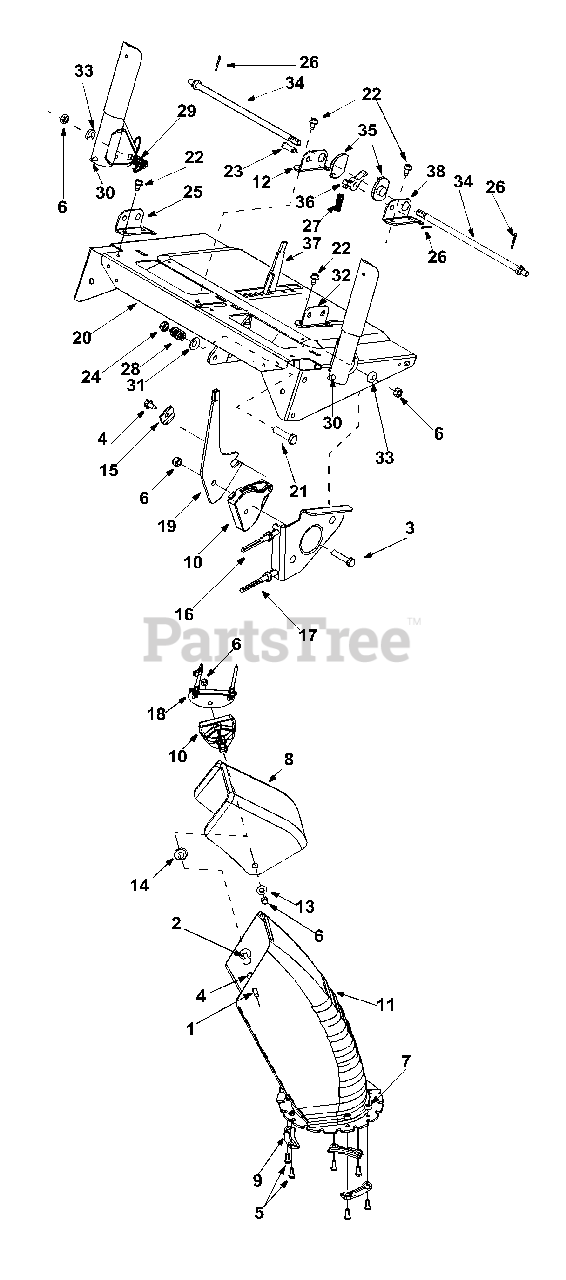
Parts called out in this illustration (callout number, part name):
1	Carriage Screw
2	Carriage Bolt 5/16-18 x 1.75"
3	Hex Bolt 5/16-18 x 1.5"
4	Hex AB Screw 1/4-14 x .625"
5	Hex Screw 1/4-20 x .75"
6	Hex Lock Nut
7	Hex Flange Lock Nut
8	Upper Chute
9	Chute Flange Keeper
10	Cable Guide: Chute Tilt
11	Lower Chute
13	5/16 Washer
14	Flat Washer
15	Special Washer
16	Chute Control Cable
17	Chute Cable w/Clip
21	Hex Bolt 3/8-24 x 1.5"
22	TT Screw 1/4-20 x 0.5"
23	Clevis Pin
24	Jam Nut
26	Cotter Pin
27	Spring
28	Spring
29	Torsion Spring
30	Rubber Bumper
31	Bell Washer
33	Special Washer
34	Cam Rod
35	Cam: Handle Lock
36	Pawl: Handle Lock
